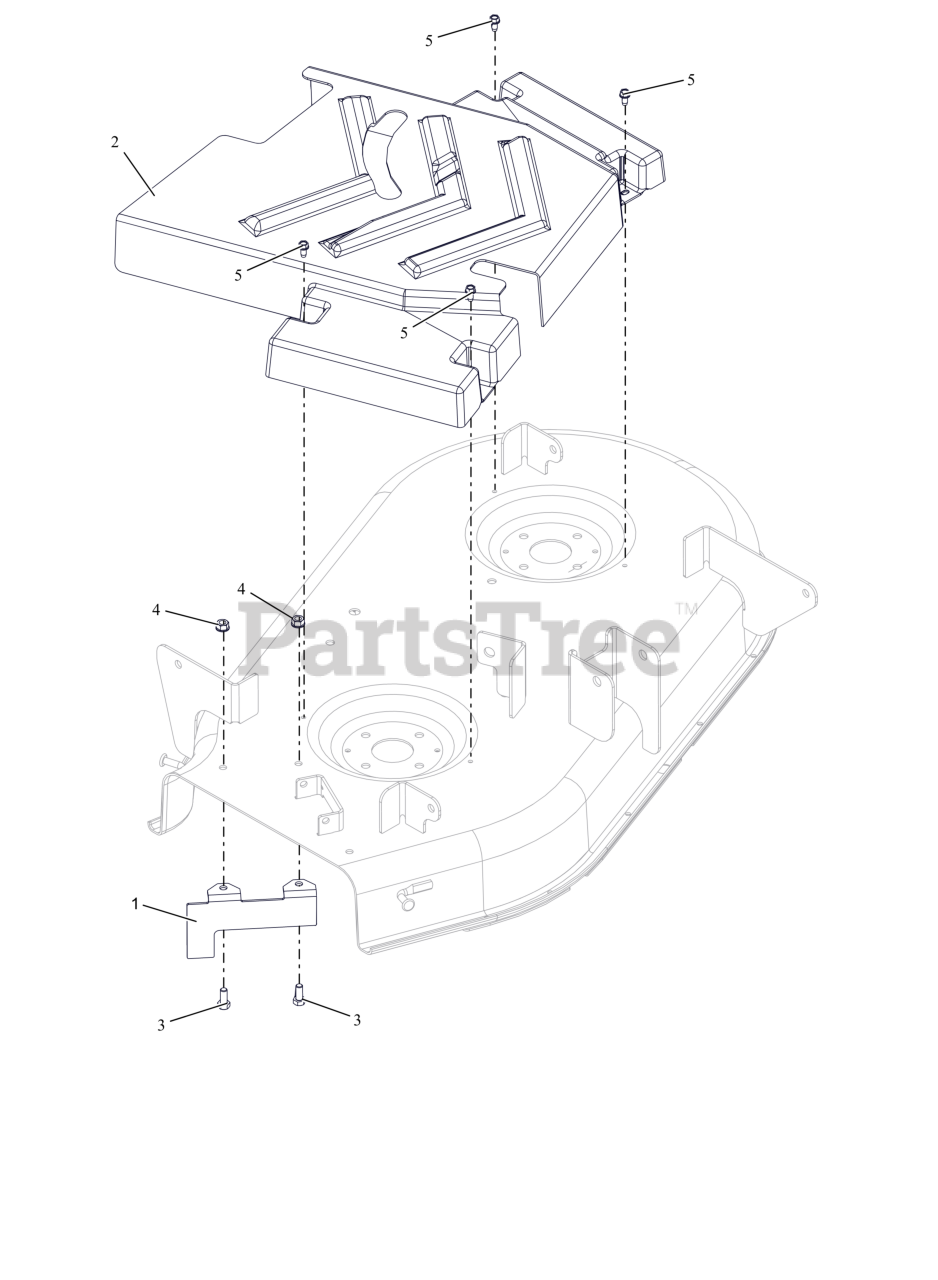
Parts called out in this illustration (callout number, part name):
1	BRKT-BAFFLE, DISCHARGE 34"
2	GUARD, CENTER EDGE 34 DECK
3	BLT,HEX .31-18X.75 G5 ZCC
4	NUT,LK-CTR-FLG .31-18 GF ZCC
5	SCR-TAP .25-20X.50 HWH ZCC
